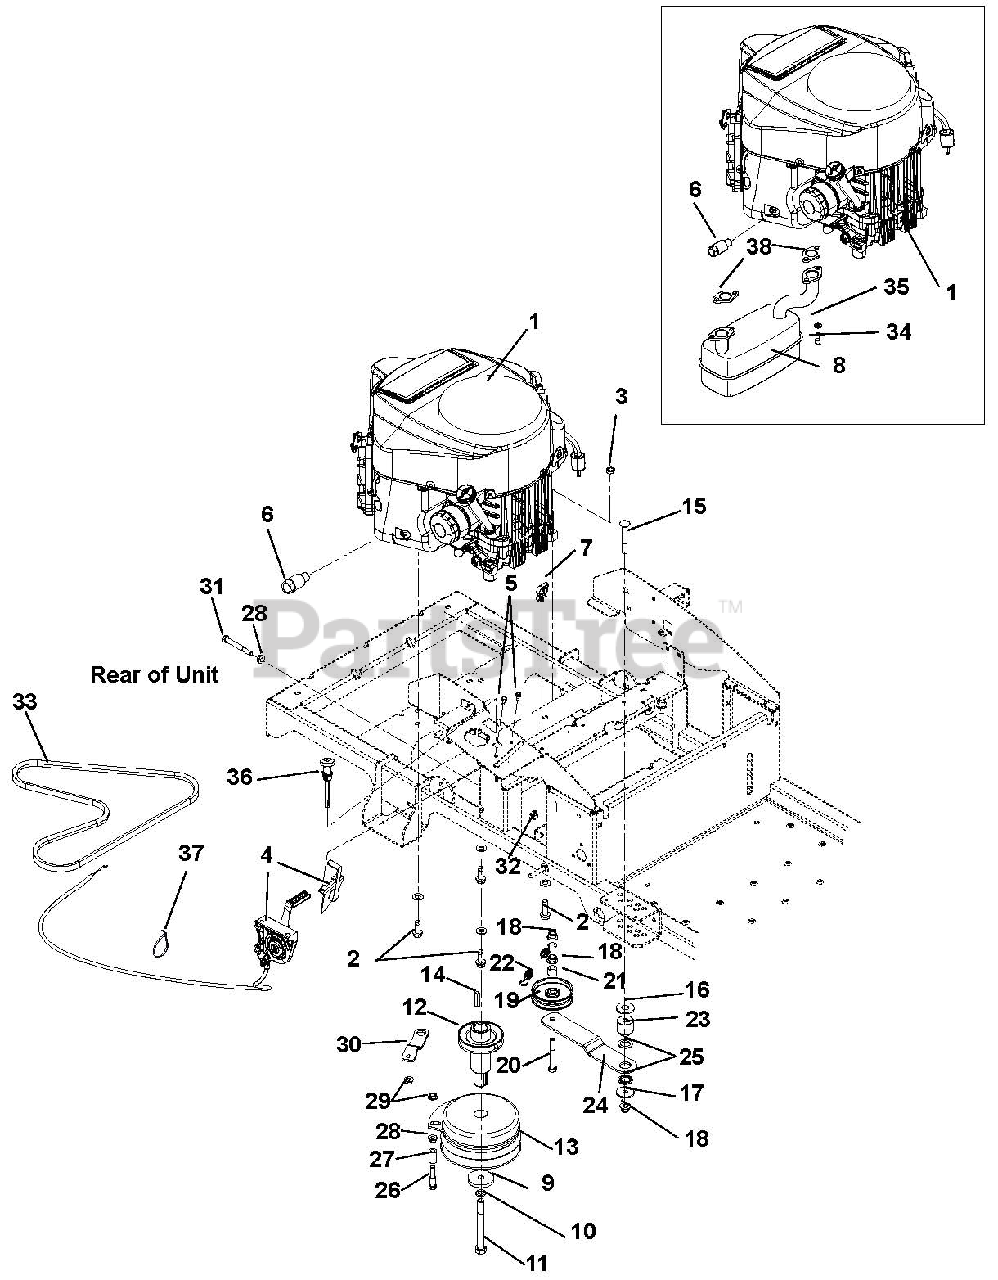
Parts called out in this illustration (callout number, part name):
1	ENGINE, KOHLER TWIN 21HP
1	ENGINE, KOHLER TWIN 19 HP
2	@SCR-TAP .38-16X1.25 HWH TR YZ
3	@NUT-LK-CTR-JAM .375-16 YWZC
4	CABLE, THROTTLE
5	@SCR-TAP 10-24X.50 HWH TR YWZC
6	DRAIN, OIL
7	WIRE CLIP
8	MUFFLER, KOHLER TWIN
9	WSHR-FL-STL .469X2.00X.25 YWZC
10	@WSHR-LK .44X.109 REG YWZC
11	BLT-HEX .44-20X4.50 GR8 YWZC
12	WLDMT, CRANKSHAFT EXTENSION
13	CLUTCH, 105 FT*LB MONO POLE
14	KEY-SQ .25 X 1.25 X .25 SAE
15	@BLT-RDHDSQNK .38-16X2.75 G5YZ
16	@WSHR-FL-STL.563X1.38X.109YWZC
17	WSHR-FL-STL .406X1.375X.135 YZ
18	@NUT-LK-NYL-FLG .38-16 YWZC
19	PULLEY, ENGINE CLUTCH 03608
20	@BLT-HEX .38-16X2.75 GR5 YWZC
21	BSHG-SLV .391X.688X.52 PM
22	SPRING, EXTENSION
23	SPACER, GROUND DRIVE IDLER
24	IDLER ARM, GROUND DRIVE
25	BUSHING, IDLER ARM
26	SCR-CAP .31-18X1 3/4 S/HD YWZC
27	SPACER, RUBBER 5/16 IDX1.0 LG
28	@NUT-SPNLK-FLG .312-18 YWZC
29	@NUT-LK-TOP-FLG .31-18 YWZC
30	BRKT, CLUTCH STOP
31	@BLT-HEX .31-18X2.75 GR5 YWZC
32	@NUT-LK-NYL-FLG .31-18 YWZC
33	V-BELT, HA-RAW EDGE
34	SCR-CAP .31-18X.88 S/HD G8 ZCC
35	@WSHR-LK .31X.078 REG YWZC
36	CABLE, CHOKE (SNAP IN)
37	CABLE TIE LG 5-1/2
38	GASKET, MUFFLER COURAGE TWIN
